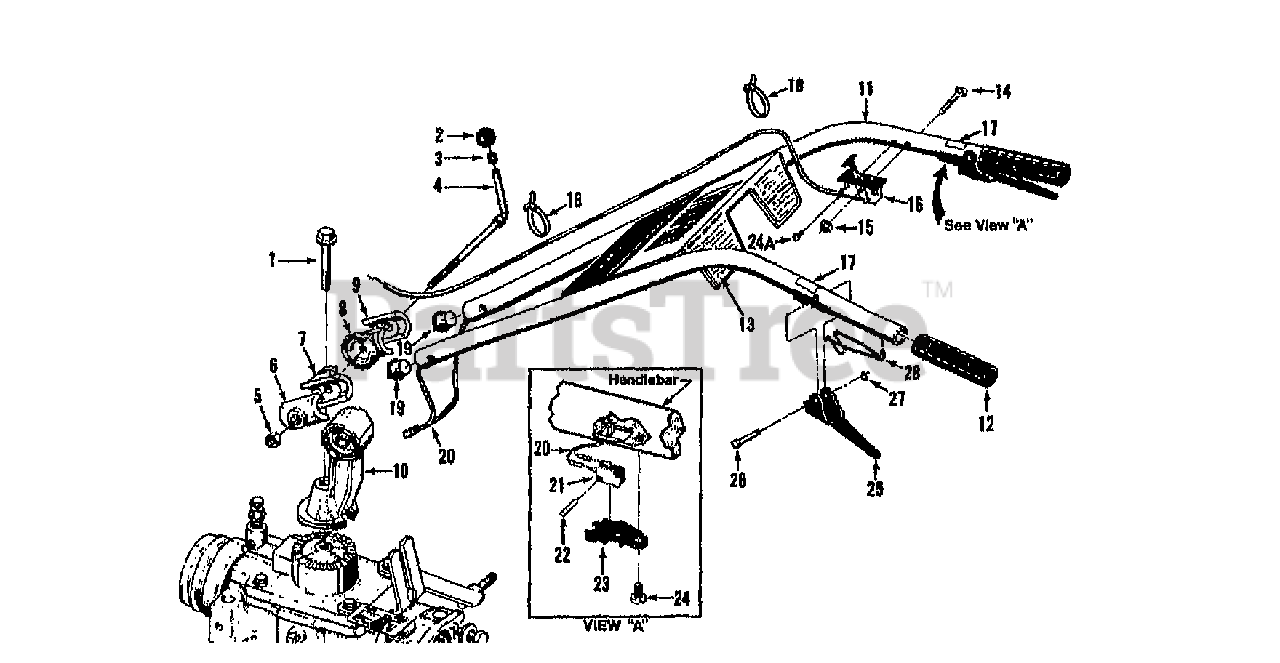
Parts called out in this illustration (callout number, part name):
1	BOLT 1/2-13X3.5 FH GR5
2	KNOB-CONTROL (INCL. 3)
3	RING-TOLERANCE .5325 ID
4	STUD-H/BAR W/NUT & RING (INCL. 2,3 & 5)
5	NUT-HEX JAM 1/2-13
6	CLAMP-LH HORSE 1021-1
7	RATCHET-H/BAR RED 2542-1
8	RATCHET-RH RED HORSE 2542-2
9	CLAMP-RH HORSE 1021-2
10	BASE-H/BAR RED 2534A
11	ASSM-HANDLEBAR W/GRIPS (INCL. 2 OF EA. 12, 17 & 28 AND ONE 13)
12	GRIP-H/BAR SMOOTH
13	DECAL-CONTROL PANEL HORSE
13	DECAL-CONTROL PANEL (11HP)
14	BOLT-CH 1/4-20X2.00 ZP
15	NUT-HF/LK 1/4-20 ZP
16	CABLE-THROTTLE 7 I/C B&S {12068/069/080/081/087}
16	CABLE-THROTTLE 7&8 B&S {12074/075/088/089/090}
16	CABLE-THROTTLE 8HP OPC {12070/071/082/083}
17	DECAL-FWD INTERLOCK
18	TIE-RED
19	RETAINER-HARNESS H/B OPC
20	HARNESS-WIRE OPC HORSE
21	SWITCH-H/B OPC
22	PIN-LK .11X.58 HORSE OPC
23	HOUSING-SWITCH OPC
24	SCR-HW M10-24X.5 STH ZP
24A	SCR-PHS M10-32X.5 STH ZP
25	LEVER-HORSE OPC
26	PIN-PIVOT OPC LEVER
27	RING-KLIP 5304-25
28	SPRING-H/B LEVER
